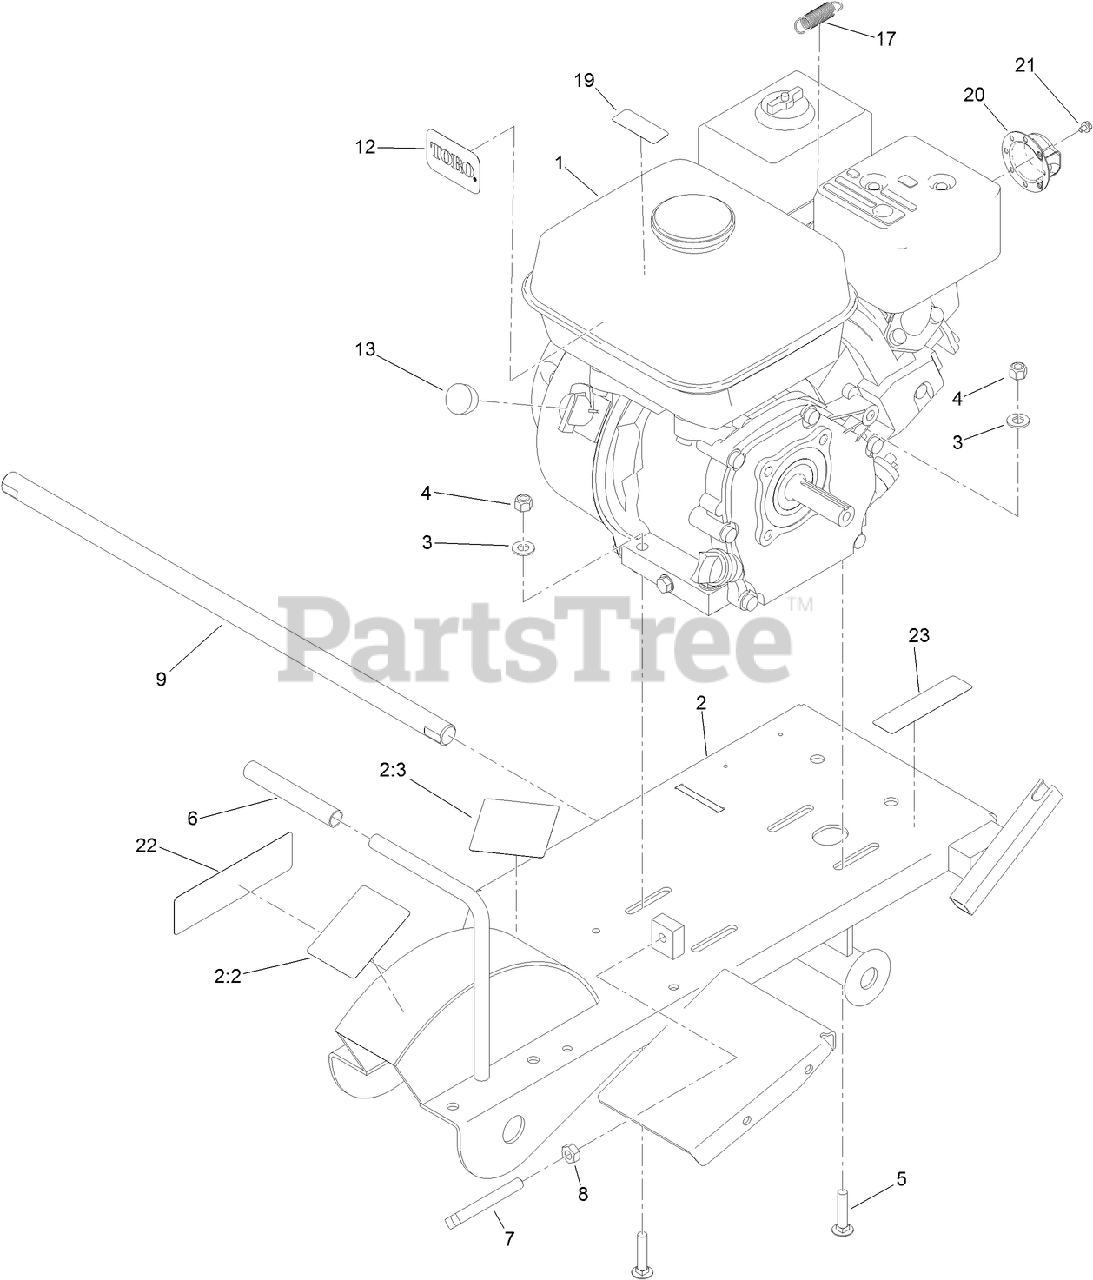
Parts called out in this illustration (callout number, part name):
2	FRAME ASM
2:2	DECAL-CAUTION
2:3	DECAL-DANGER
3	WASHER-FLAT
4	NUT-LOCK, NI
5	BOLT-CARR
6	GRIP-RUBBER
7	SCREW-SET, SQH
8	NUT-HEX
9	BAR-AXLE, WHEEL
12	DECAL
13	PLUG-ENGINE
17	SPRING-EXTENSION
19	DECAL-WARNING, ETHANOL
20	DEFLECTOR
21	SCREW-HWH
22	DECAL-ROTATE TOOTH
23	DECAL-ARRESTER, SPARK
